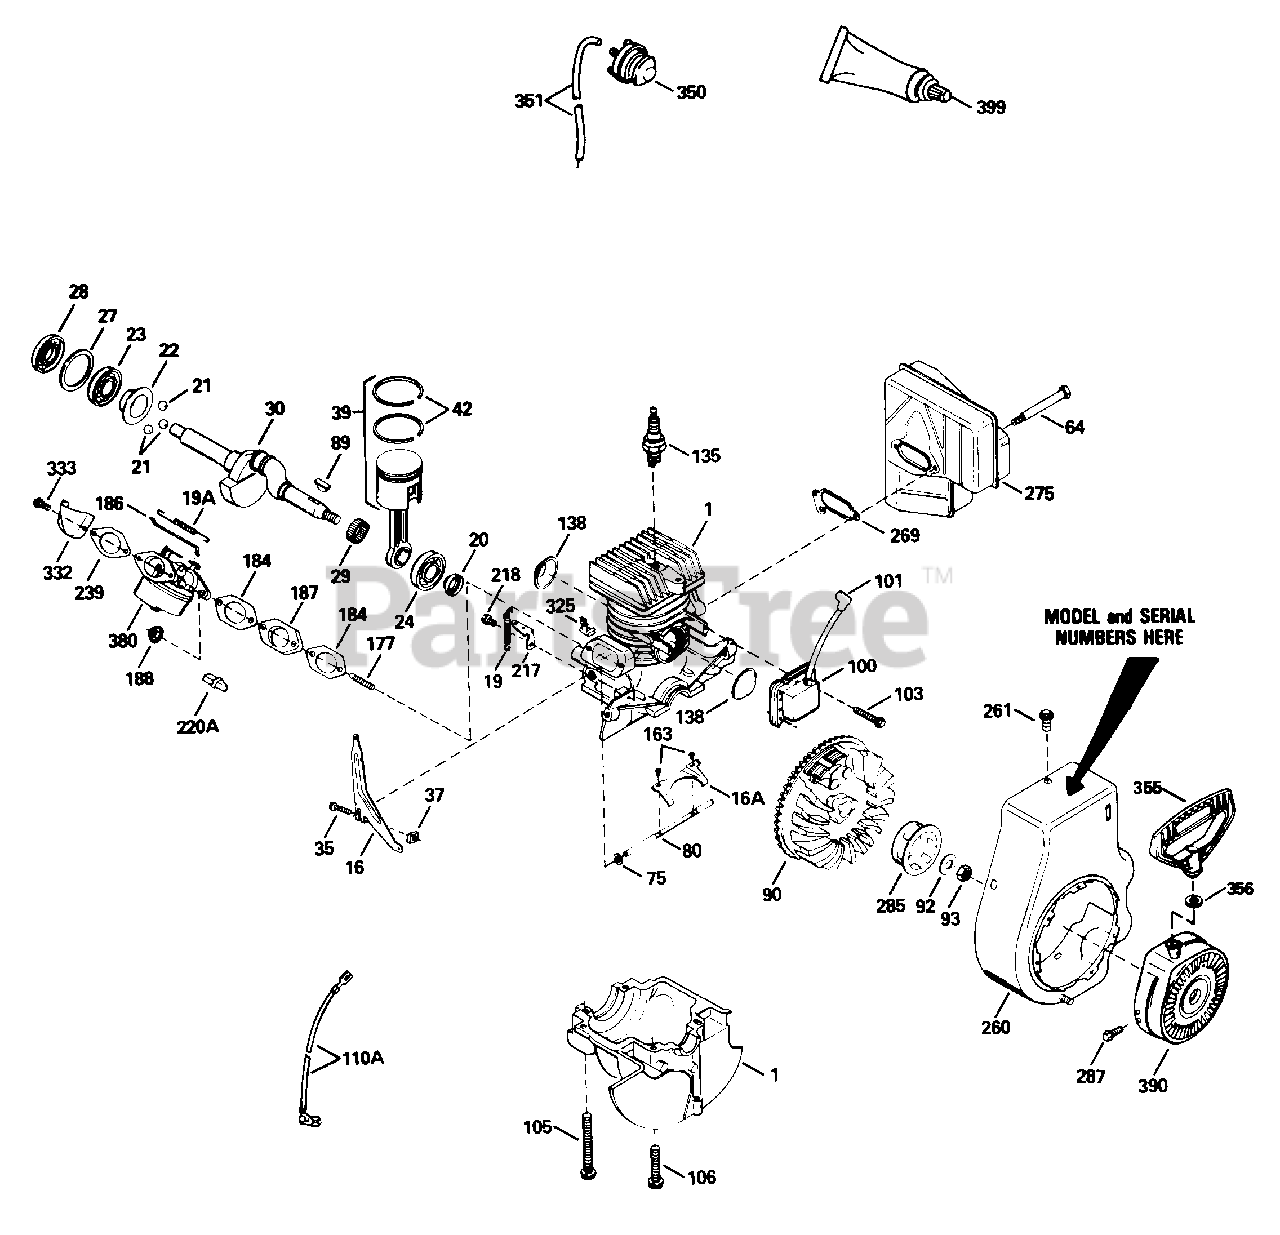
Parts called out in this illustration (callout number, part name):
1	Cylinder & Cover Ass'y.
16	Lever, Governor
16A	Lever, Governor
19	Spring, Governor
19A	Spring, Backlash
20	Seal (Flywheel End)
22	Ring, Slide
23	Bearing, Ball (PTO End)
24	Bearing, Ball (Magneto End)
27	Retainer, Bearing
28	Seal (PTO End)
29	Bearing Strip (31 Needles)
30	Crankshaft
35	Screw, Hex Washer Hd., 10-32 x 3/4
37	Nut, Square
39	Piston & Rod Ass'y.
42	Ring Set, Piston
64	Screw, Muffler (5/16-18 x 3-13/64)
80	Shaft, Governor
89	Key, Flywheel
92	Washer, Belleville
93	Nut, Flywheel
100	Solid State Ass'y.
101	Cover, Spark Plug
103	Screw, Torx Washer Hd. Sems, 10-24 x 1
105	Screw, Hex Hd., 5/16-18 x 2-3/16
106	Screw, Hex Hd., 5/16-18 x 1-5/8
135	Plug, Spark
138	Cover, Port
163	Screw, Pan Washer Hd., 4-40 x 3/16
177	Stud, Carburetor Mounting
184	Gasket, Carburetor
186	Link, Governor
187	Spacer, Carburetor
188	Nut, Whizlock
217	Lever, Speed Control
218	Screw, Hex Washer Hd. Taptite, 8-32 x 1/2
220A	Knob, Control
239	Gasket, Filter Base
260	Housing, Blower
261	Screw, Hex Washer Hd. Taptite, 5/16-18 x 5/8
269	Gasket, Muffler
285	Hub, Starter
287	Screw, Hex Washer Hd., 8-32 x 1/2
325	Clip, Spring
332	Baffle, Carburetor
333	Screw, Pan Hd. Torx, 10-32 x 3/8
350	Primer Ass'y.
351	Line, Primer
355	Handle, Mitten Grip
380	Carburetor
390	Starter, Rewind
399	Gasket Eliminator
